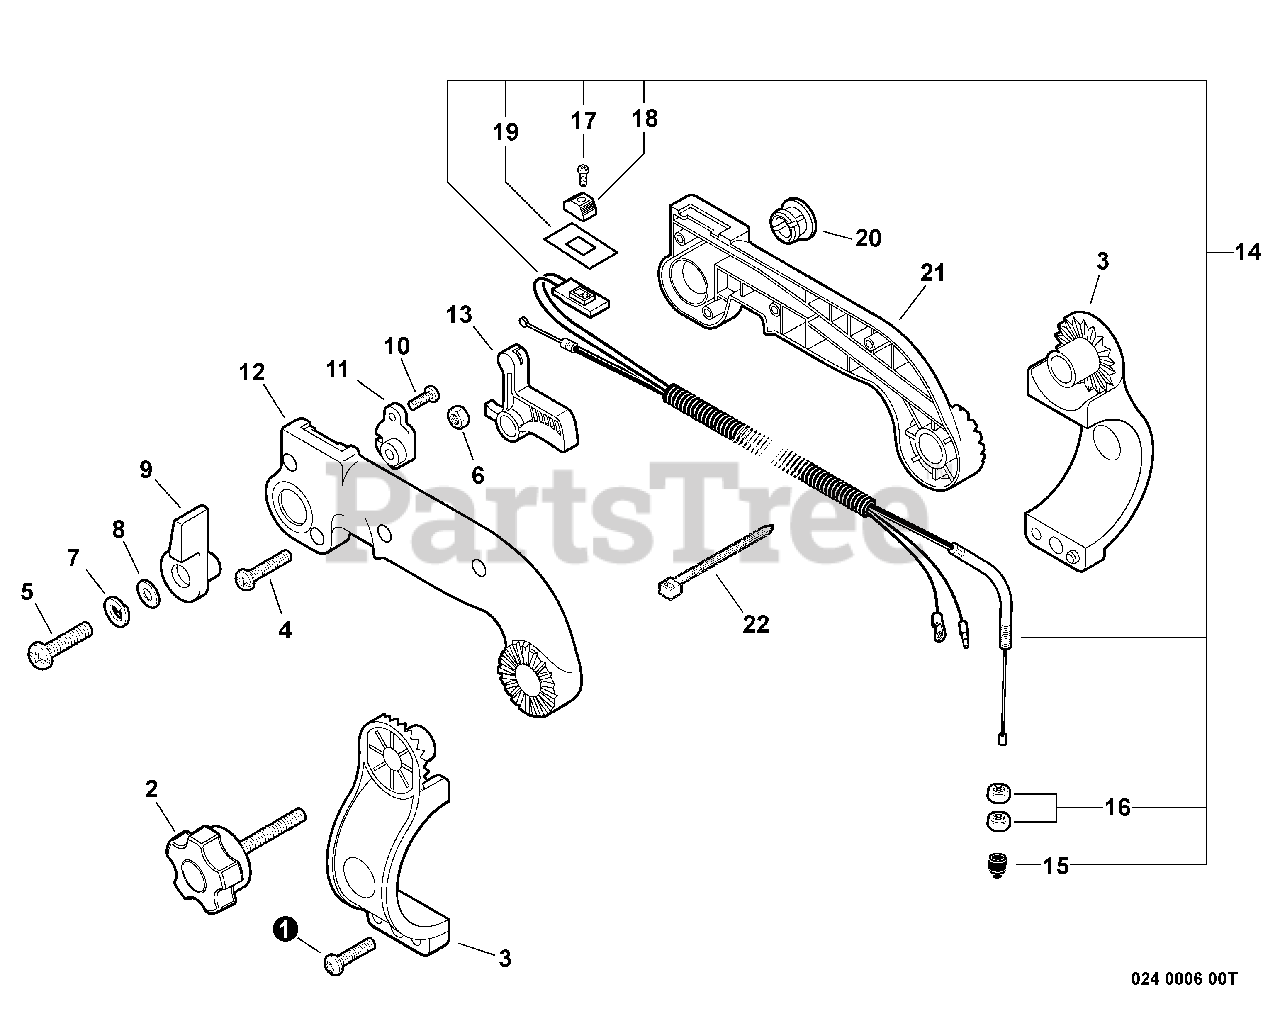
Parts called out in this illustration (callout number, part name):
1	SCREW, TAPPING 5×20
2	KNOB, SCREW
3	BRACKET KIT, HANDLE
4	SCREW 4×22
5	SCREW 6×20
6	NUT, HEX M6
7	WASHER, SPRING 6
8	WASHER 6.5×13×1
9	CONTROL, THROTTLE
10	SCREW 4×10
11	BRACKET, THROTTLE
12	CONTROL HANDLE - LEFT
13	TRIGGER, THROTTLE
14	CABLE ASSY, CONTROL
15	CAP, DUST
16	NUT 6 MM
17	SCREW 3×10
18	KNOB, SWITCH - ORANGE
19	LABEL, SWITCH
21	CONTROL HANDLE - RIGHT
22	STRAP, TIE
